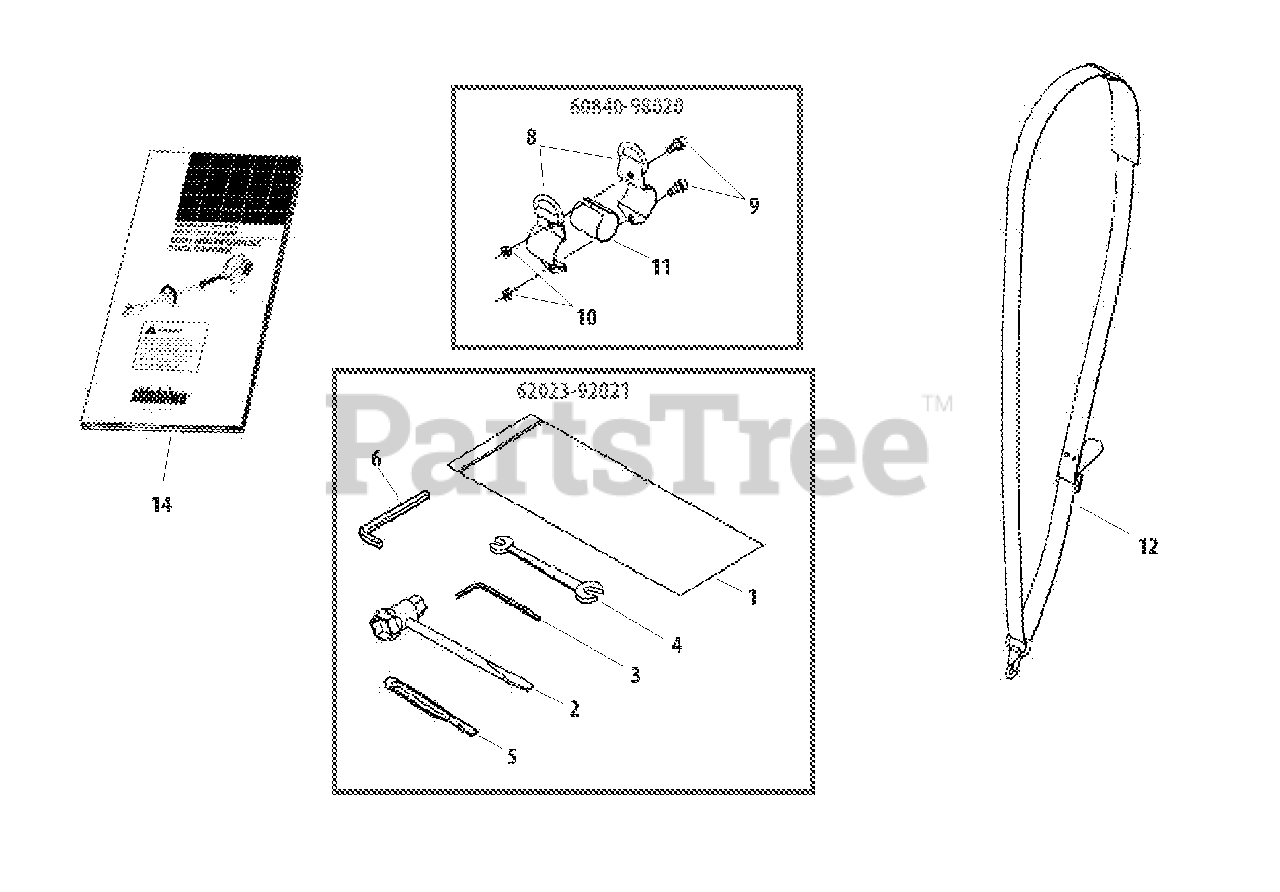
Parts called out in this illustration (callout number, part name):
1	BAG, TOOL
2	T-WRENCH 13×19 MM
3	WRENCH, ALLEN 4 MM
4	SPANNER 8×10
5	SCREWDRIVER, PLASTIC
6	WRENCH, ALLEN 3 MM
8	HANGER SET
9	BOLT M5×12
10	NUT M5
11	SPACER
12	HARNESS ASSY
14	OWNER'S MANUAL
60840-98020	HANGER ASSY
62023-92021	SERVICE TOOL KIT
